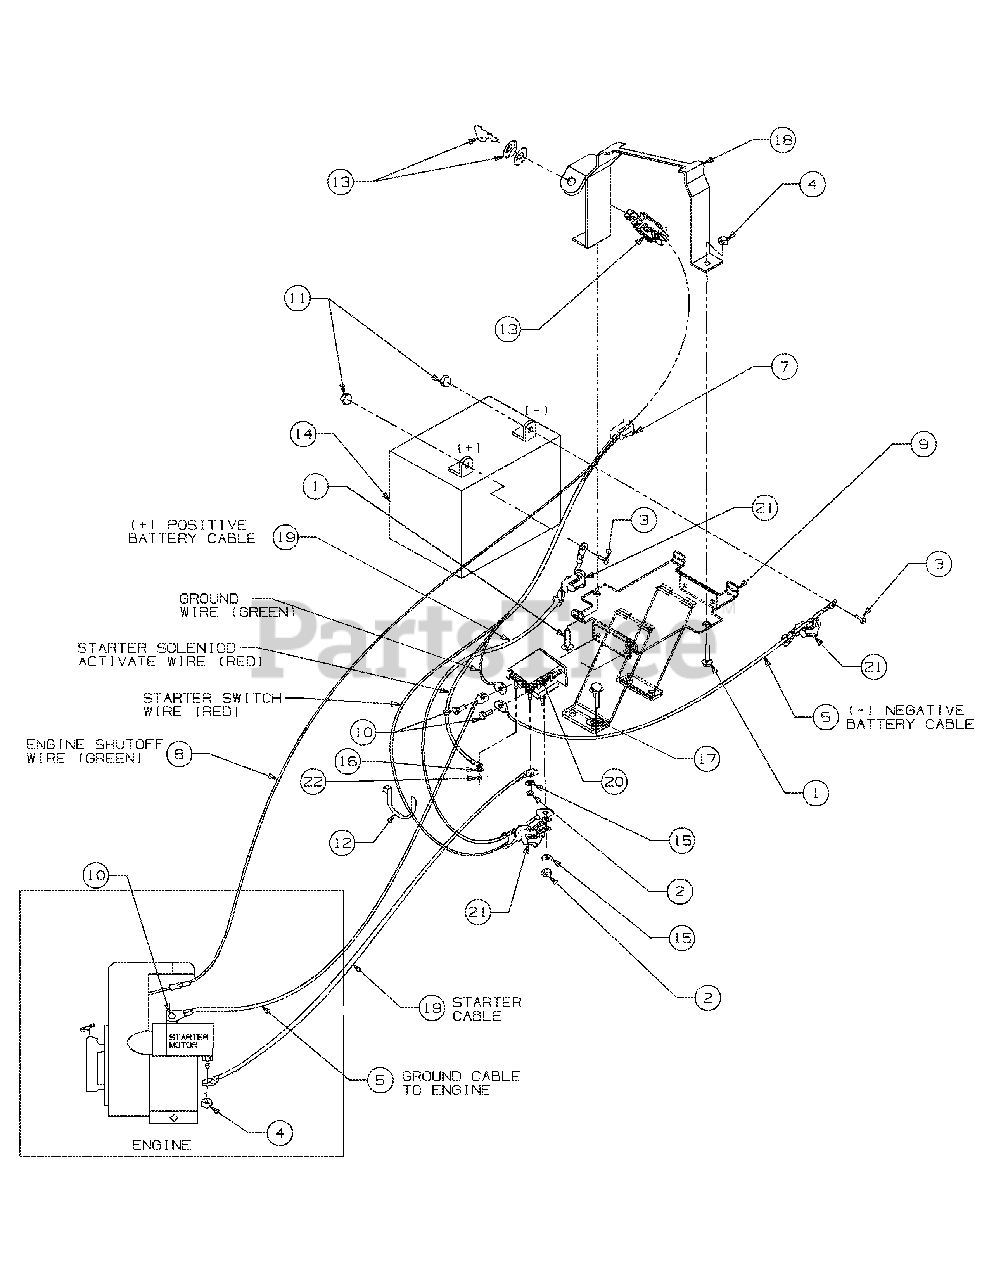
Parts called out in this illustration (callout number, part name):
1	Carriage Screw, 1/4-20 x 1.25
2	Hex Nut, 5/16-24
3	Flange Screw, 1/4-20 x .625
4	Hex Locknut, 1/4-20
5	Cable (ground wire to starter motor bracket)
7	Wire Harness Assy.
8	Ground Wire Assy. (shut off)
11	Hex Nut, 1/4-20
12	Cable Tie
13	Ignition Switch
14	Battery, 270 CCA
15	Lock Washer 5/16
16	Lock Washer, #10
17	External Lock Washer, 5/16
18	Keyswitch Clamp
19	Cable (solenoid to starter motor)
20	Solenoid (Incl. nuts and washers for cable & wires)
21	Boot, Insulating
22	Hex Locknut, #10-32
